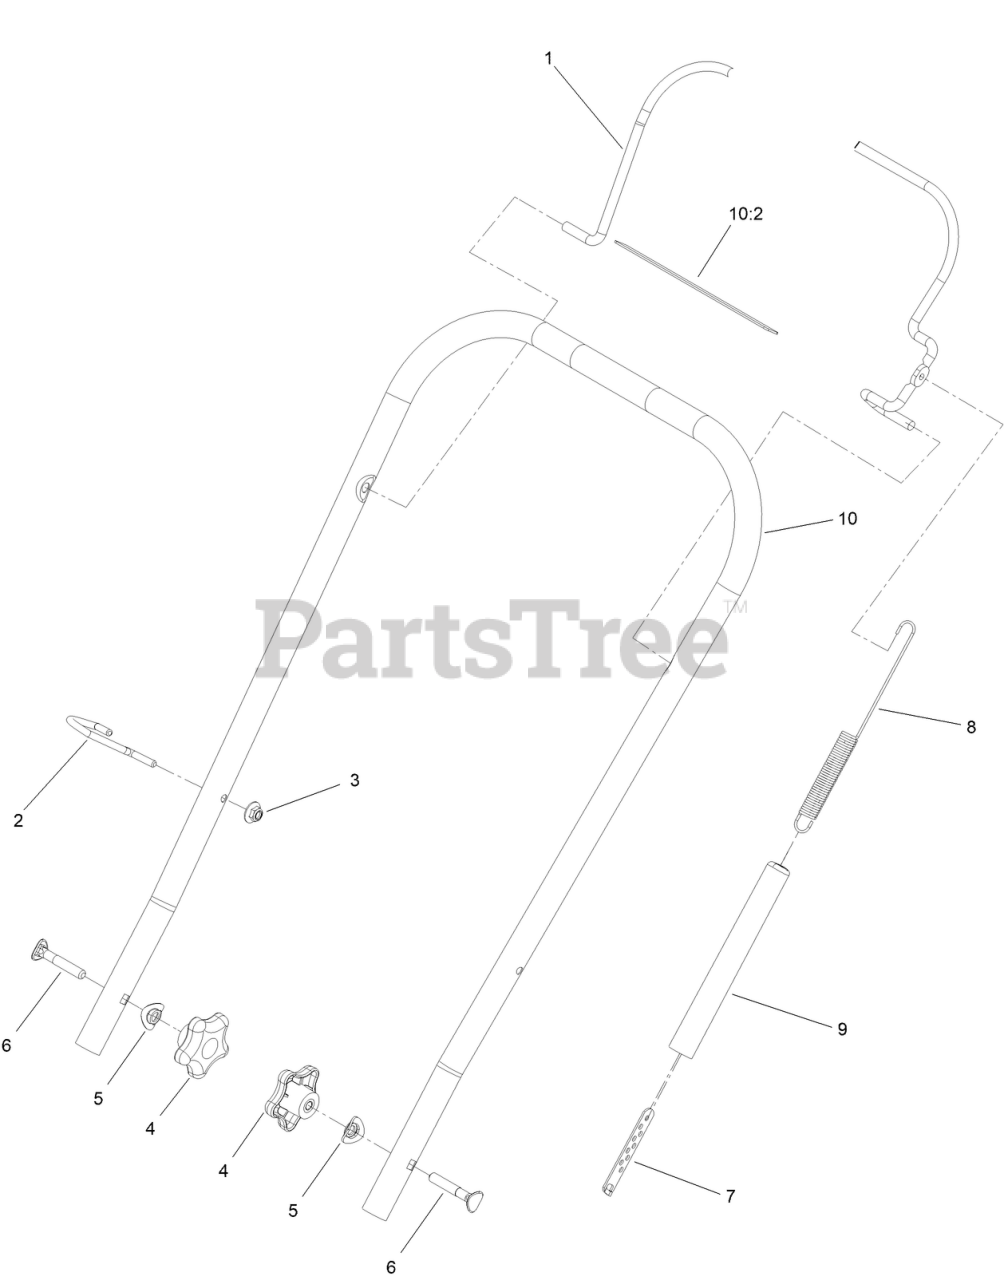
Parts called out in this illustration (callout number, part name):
1	BAIL-CLUTCH
2	GUIDE-ROPE
3	NUT-HF
4	KNOB-HANDLE
5	WASHER
6	SCREW-HANDLE
7	ADJUSTER-CLUTCH CABLE
8	SPRING-CLUTCH
9	COVER-SPRING
10	UPPER HANDLE ASM
10:2	DECAL-SAFETY
